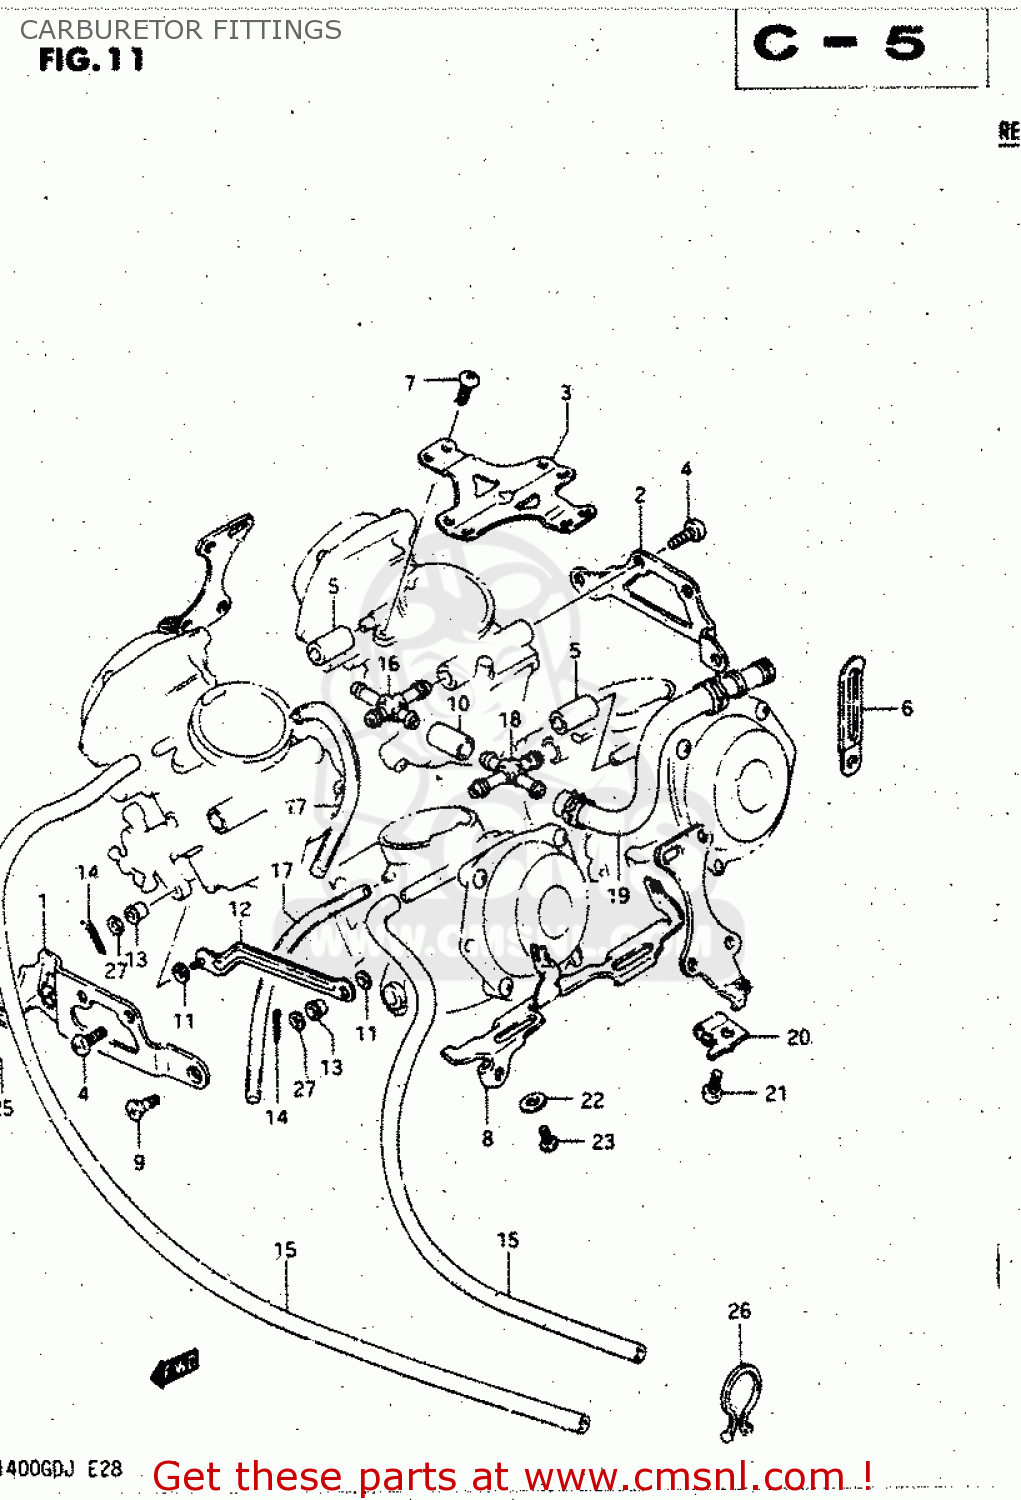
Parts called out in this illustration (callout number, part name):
1	PLATE
2	PLATE
3	PLATE
4	SCREW
5	HOSE,CARBURETOR
6	CLIP
7	SCREW 5X10
8	LEVER
9	SCREW
10	HOSE
11	WASHER,CHOKE LEVER
12	PLATE
13	RING
14	COTTER
15	HOSE
16	NIPPLE
17	HOSE
18	NIPPLE
19	HOSE ASSEMBLY
20	PLATE
21	SCREW 5X12
22	WASHER
23	SCREW
24	ADJUSTER,THROTTLE
25	SPRING
26	CLIP
27	WASHER
